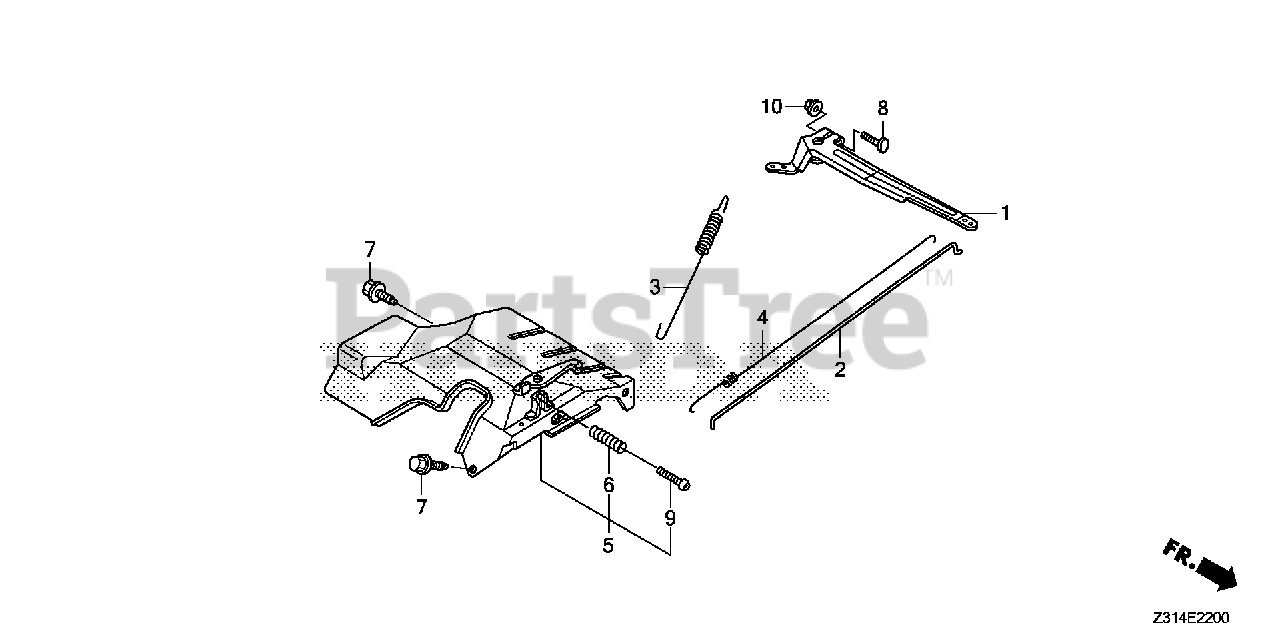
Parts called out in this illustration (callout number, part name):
1	ARM, GOVERNOR
2	ROD, GOVERNOR
3	SPRING, GOVERNOR
4	SPRING, THROTTLE RETURN
5	CONTROL ASSY. (COO)(FOR U.S.A.)
6	SPRING, CONTROL ADJUSTING
7	BOLT, FLANGE (6X12) (CT200)
8	BOLT, GOVERNOR ARM
9	SCREW, PAN (5X35)
10	NUT, FLANGE (6MM)
